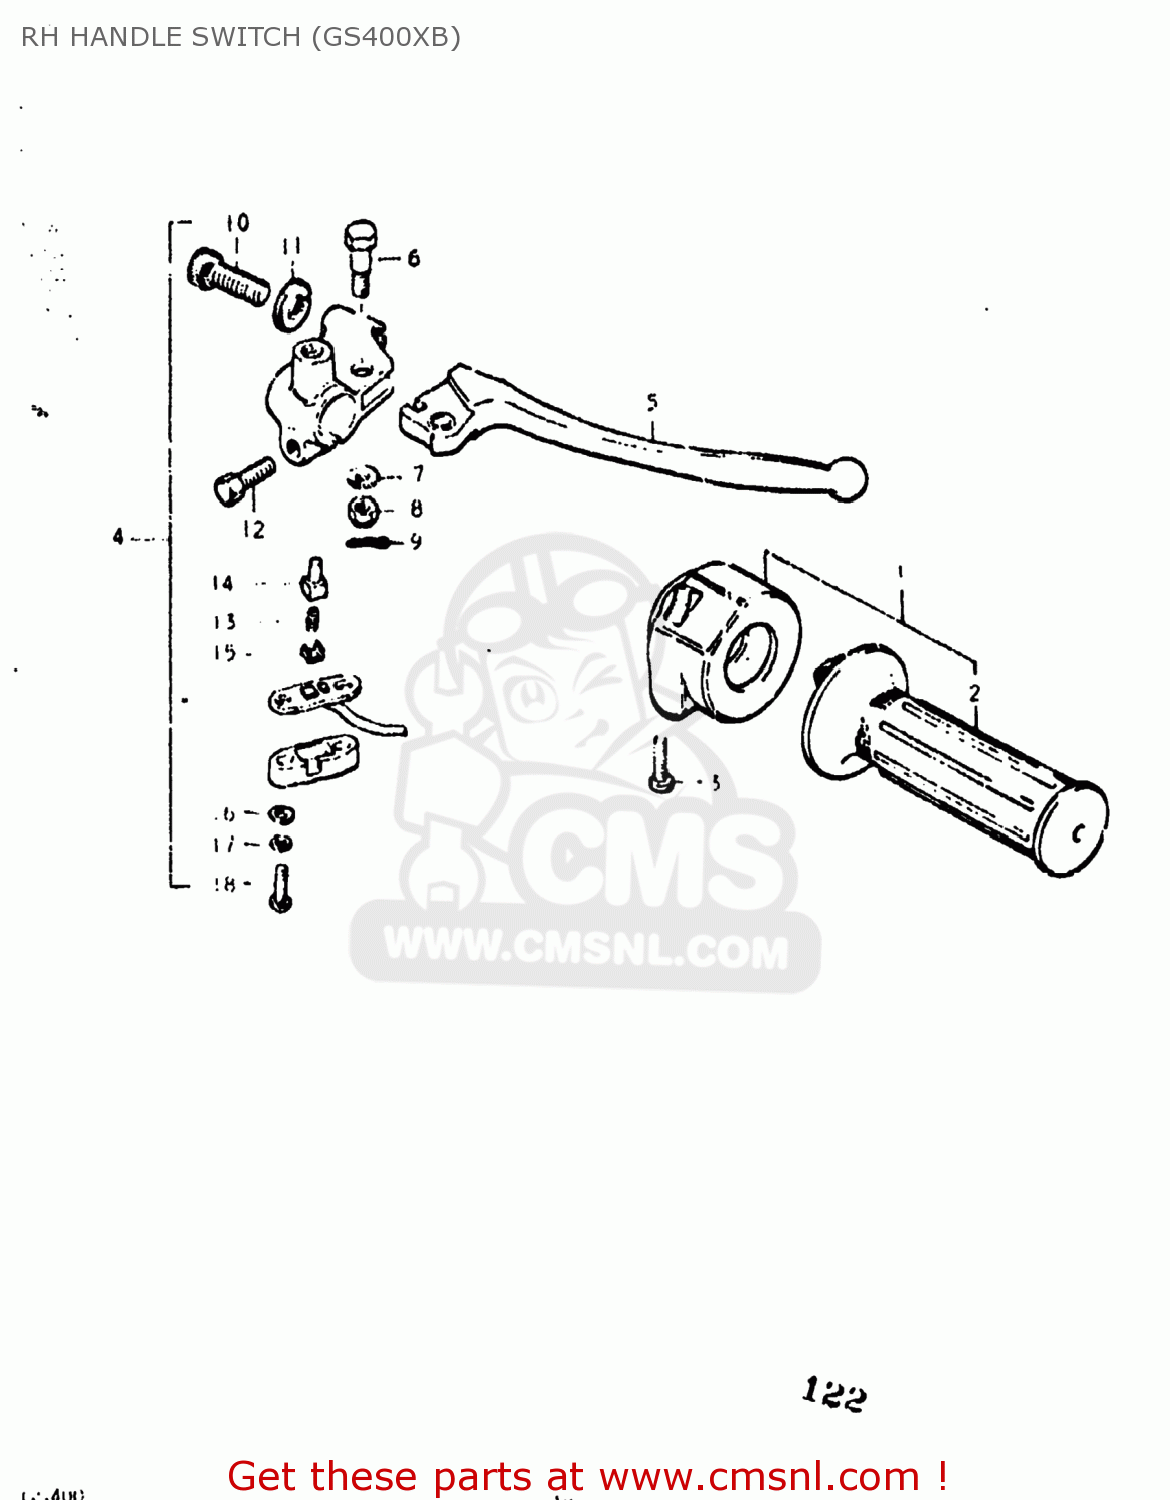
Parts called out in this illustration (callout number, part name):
1	CASE ASSEMBLY,THROTTLE
2	GRIP,THROTTLE
3	SCREW
4	LEVER ASSEMBLY,BRAKE
5	LEVER,BRAKE
6	BOLT,LEVER
7	LOCK WASHER
8	NUT,LEVER FITTNG
9	COTTER PIN
10	ADJUSTER,CABLE
11	NUT,CABLE ADJUSTER
12	BOLT
13	SPRING
14	HOLDER
15	PLATE
16	WASHER
17	LOCK WASHER
18	SCREW
